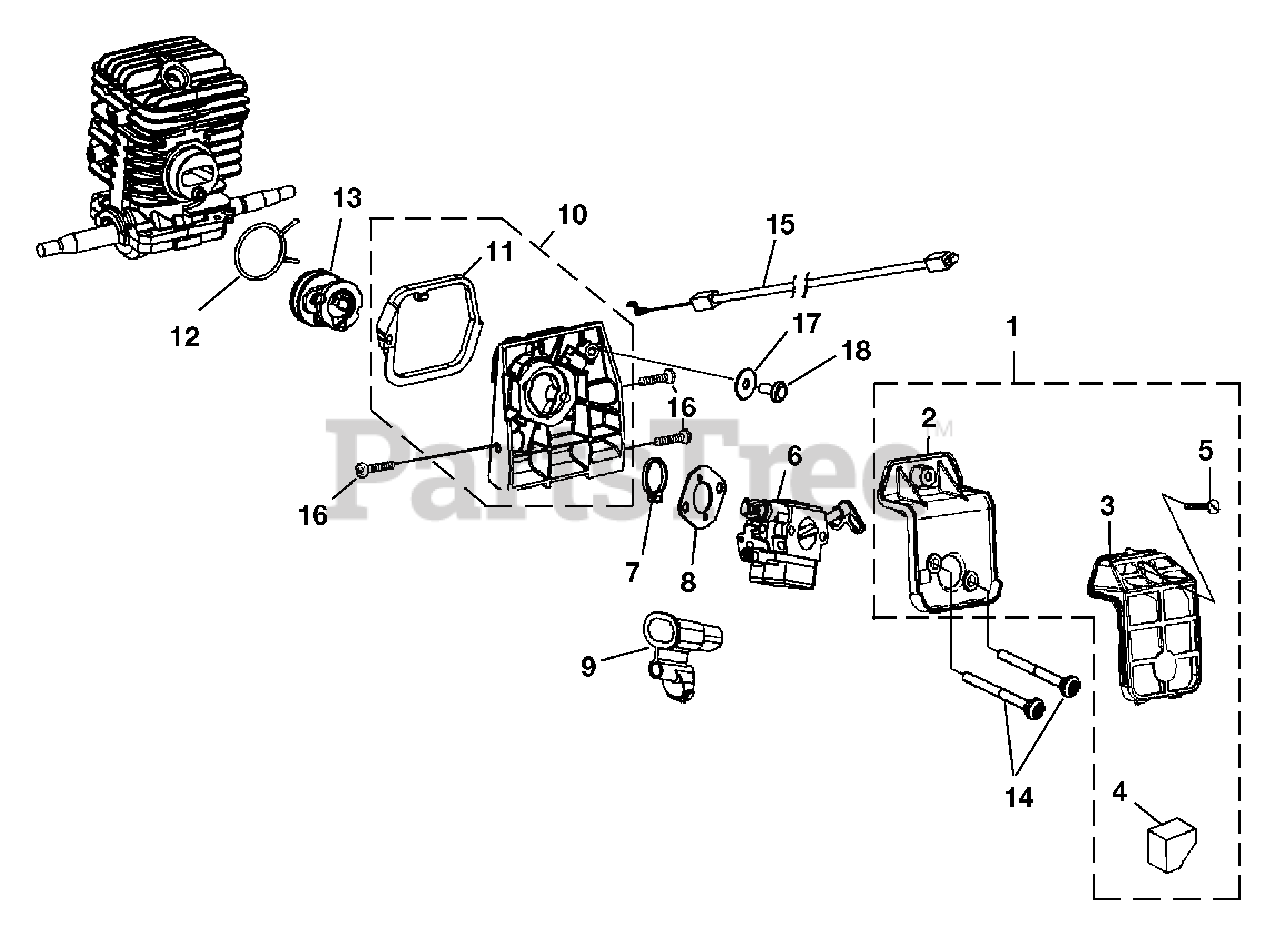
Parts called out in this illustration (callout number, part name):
1	Air Filter Kit
2	Air Filter Base
3	Air Filter Cover
4	Pre Filter
5	Screw-Slotted Pan Hd.(8-16 x 5/8")
6	Carburetor Assembly
7	Plate-Carburetor
8	Gasket-Carburetor
9	Grommet-Carburetor
10	Adaptor-Carburetor
11	Seal-Carb Adaptor
12	Clamp-Wire
13	Intake Boot
14	Screw 10-32 x 1.75
15	Throttle Cable
16	Screw-Torx
17	Washer, Retaining
18	Screw
